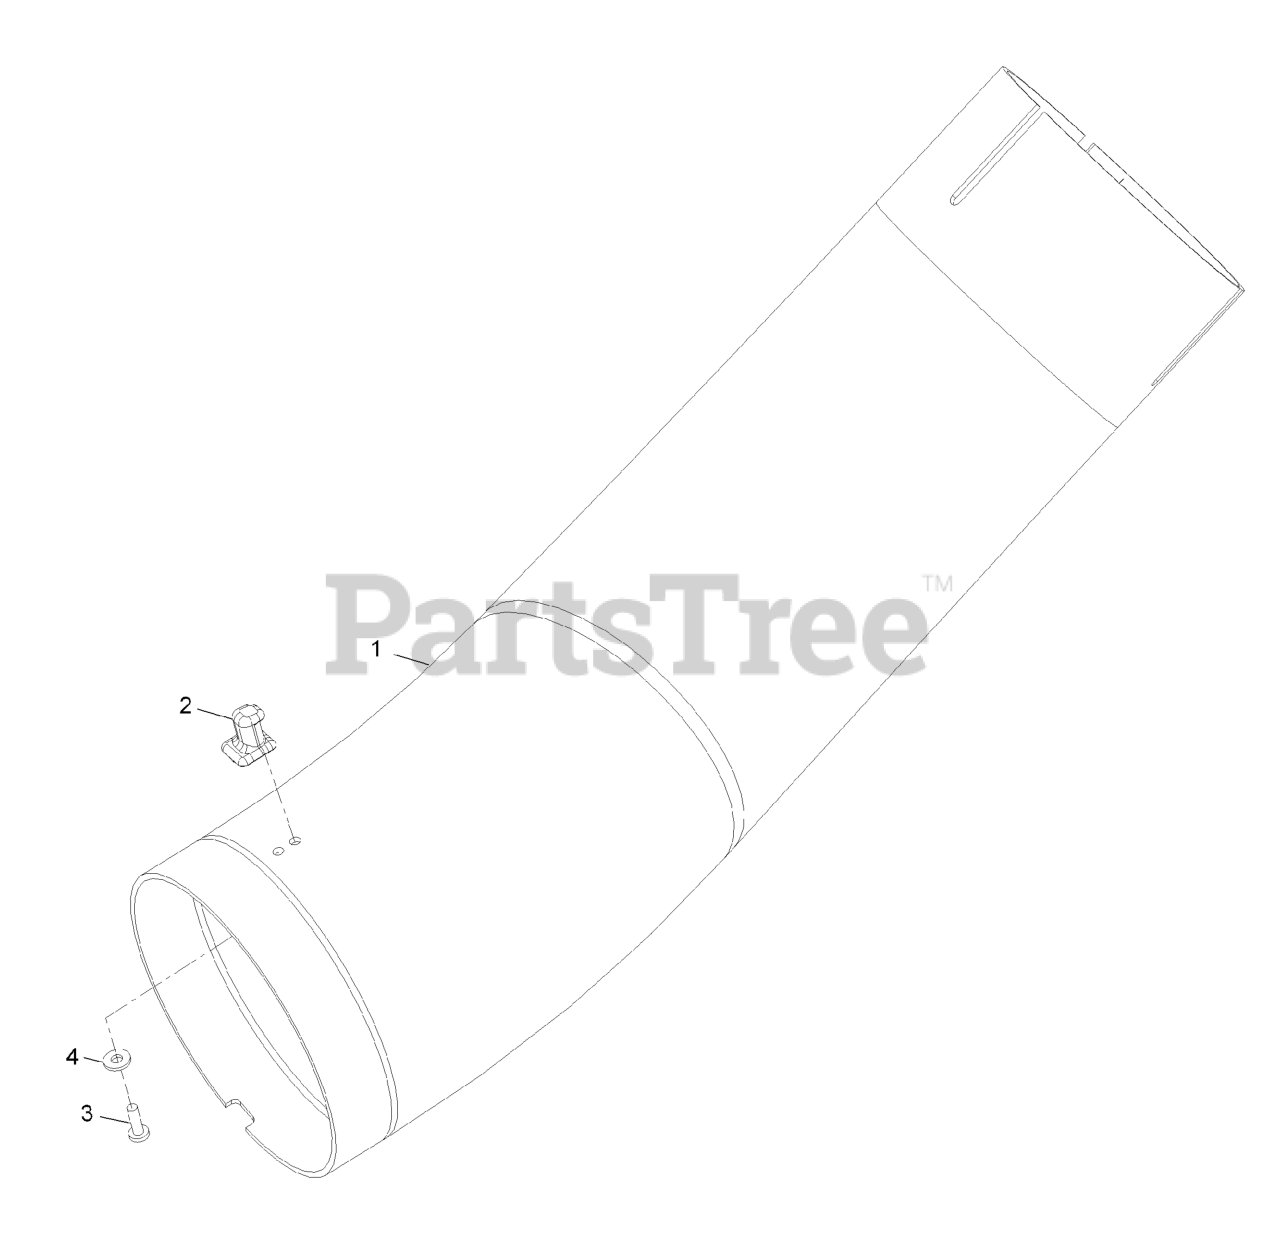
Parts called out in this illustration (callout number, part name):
1	Tube, Lower Short
2	LATCH-KEEPER
3	SCREW-PPH
4	WASHER-FLAT
